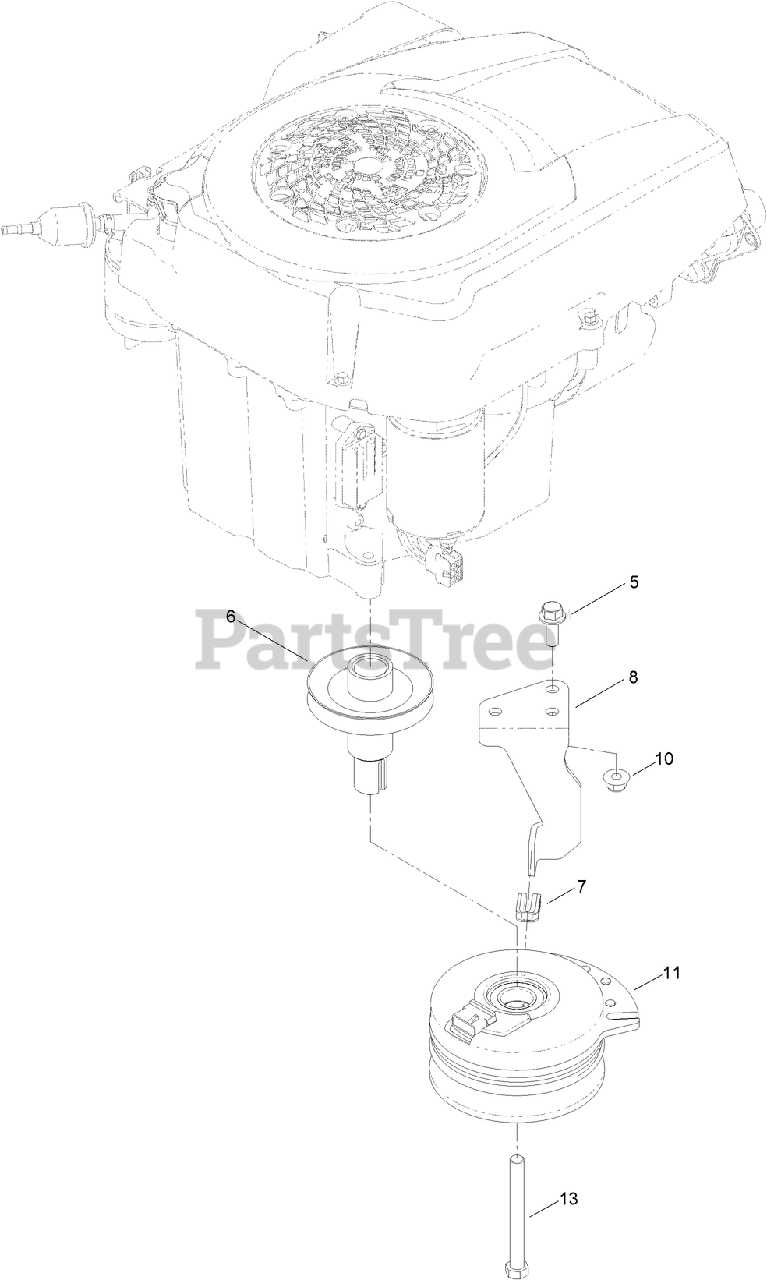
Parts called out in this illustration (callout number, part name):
5	SCREW-HHF
6	PULLEY-ENGINE
7	ISOLATOR-CLUTCH
8	STOP-CLUTCH
10	NUT-HF, NI
11	CLUTCH-ELECTRIC
13	SCREW-HH
